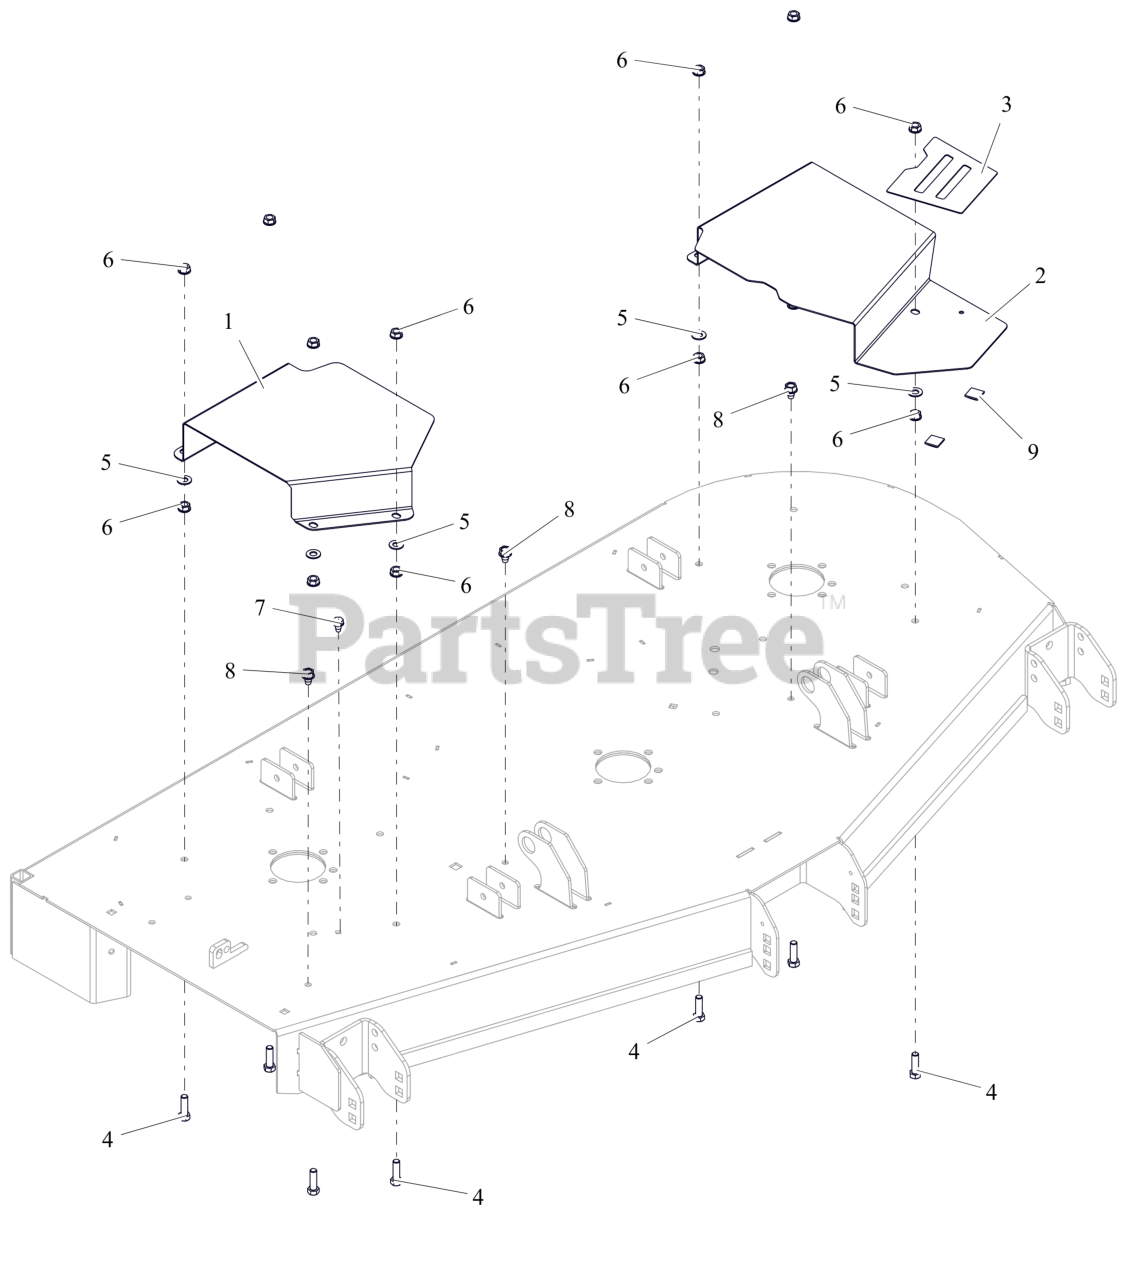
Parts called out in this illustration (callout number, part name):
1	COVER, BELT 52" & 60" RIGHT
2	COVER, BELT 60" LEFT
3	GRIP TAPE 52-60 BELT COVER
4	BLT, HEX .38-16X1.25 G5 ZCC
5	WSHR,FLT .406X.812X.065 ZCC
6	NUT, SPNLK-FLG .38-16 G5 ZCC
7	SCR,TAP .312-18X.50 HWH TR ZCC
8	SCR,TAP .375-16X.50 HWH TR ZCC
